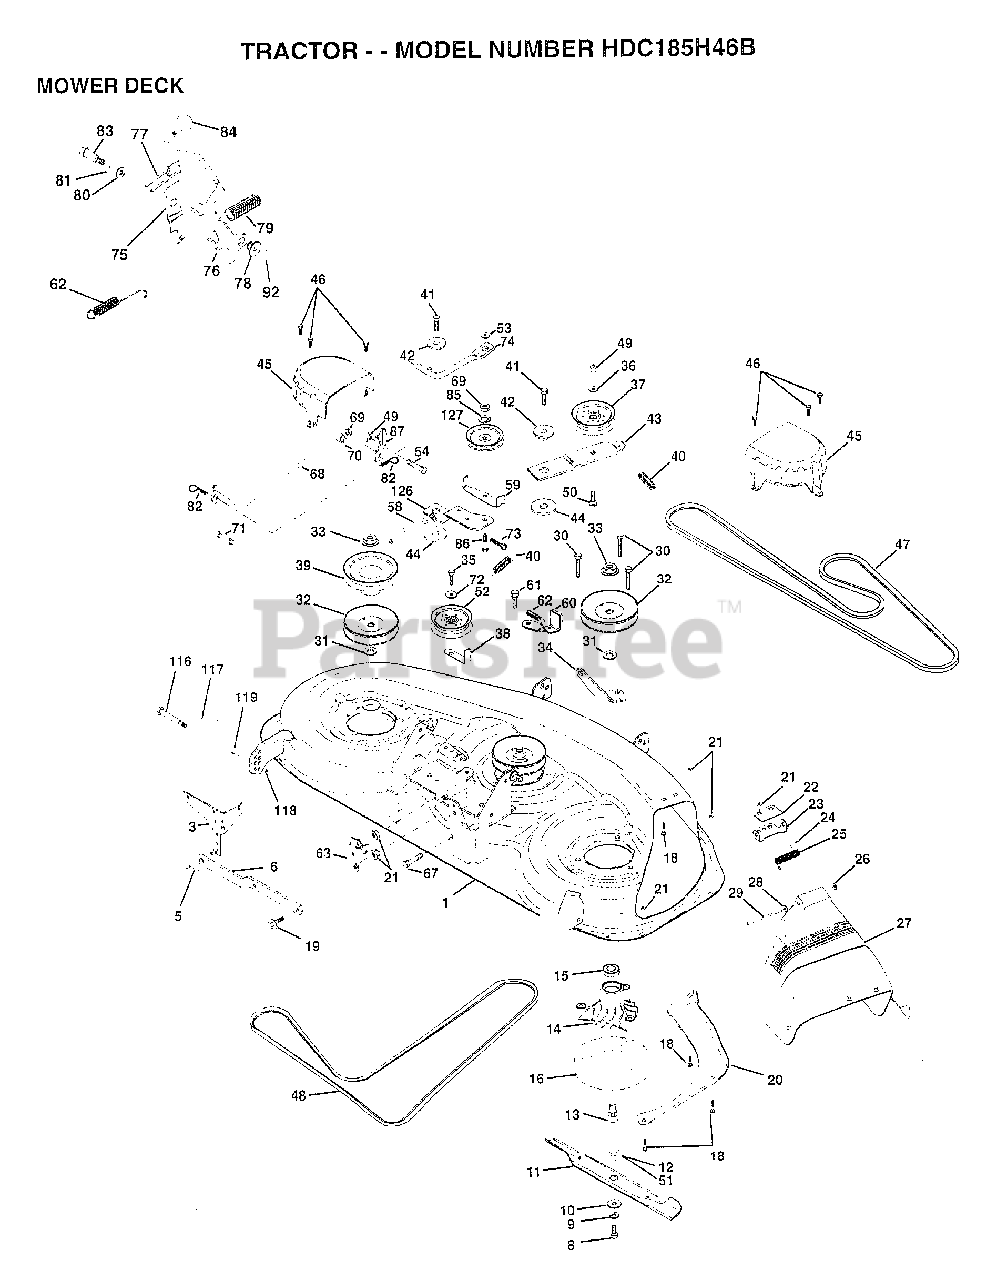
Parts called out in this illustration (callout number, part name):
1	"MOWER ASM 46"""
3	BRKT.ASM.SW.44/50
8	BLADE BOLT
10	WASHER.HARD.BLADE
11	"BLADE.HIGHLIFT46"""
12	BEARING.BALL
13	SHAFT.ASM.W/BRNG
14	HOUSING.MAND.44.V
15	BEARING
16	STRIPPER RND MWR
18	BOLT
19	BOLT SHD 5/16-18
20	BAFFFLE.VORTEX.46
22	STIFFENER BRKT
23	DEFLECTOR BRKT
24	CAP-SLEEVE LT
26	NUT PUSH M
27	SHIELD DEFLECTOR
28	WASHER
29	HINGE ROD
30	"SCREW-THD ROLL,WA"
31	WASHER
32	PULLEY.MAND.36/46
34	ANCHOR.SPRING.46
35	SCREW LT
36	WASHER
37	FLAT IDLER PULLEY
38	"KEEPER BELT,IDLER"
39	PULLEY.DRV.DCK.46
40	"SPRING.SEC.44""VEN"
41	SCREW
42	SPACER RETAINER
43	ARM.IDLER.DECK.46
44	HARDENED WASHER
45	COVER.MANDREL.46
46	SCREW.1/4-20X5/8
47	BELT-V.SEC.46.KEL
48	V BELT MOWER
50	BOLT.3/8-16X1.50
51	WASHER.FELT.
52	"PULLEY IDLER,FLAT"
58	"LINK BRAKE, 43"""
59	"GUIDE BELT,46""MOW"
60	ARM ASM BRAKE
61	BOLT.SHLD.5/16-18
62	RETURN SPRING
63	"BRKT ROD,CLUTCH"
67	BOLT
69	NUT
70	TRUNION ADJ
71	PIVOT ROD
72	WASHER
73	COTTER PIN
74	LINK CLUTCH
75	CLUTCH ARM SECOND
76	LEVER ASM-CLUTCH
77	SPRING KEEPER
78	BUSHING
79	SPRING.CLUTCH.MWR
80	WASHER
81	RING
82	RETAINER M
83	SHOULDER BOLT
84	KNOB T(3/8 HOLE)
85	LOCKWASHER
86	"BOLT CARR, SH"
87	BRACKET.EXTENSION
88	BOLT
92	NUT
116	BOLT.SHOULDER
117	WHEEL.GUAGE.MED.
118	LOCKNUT
119	WASHER
127	PULLEY.IDLER.4.25
